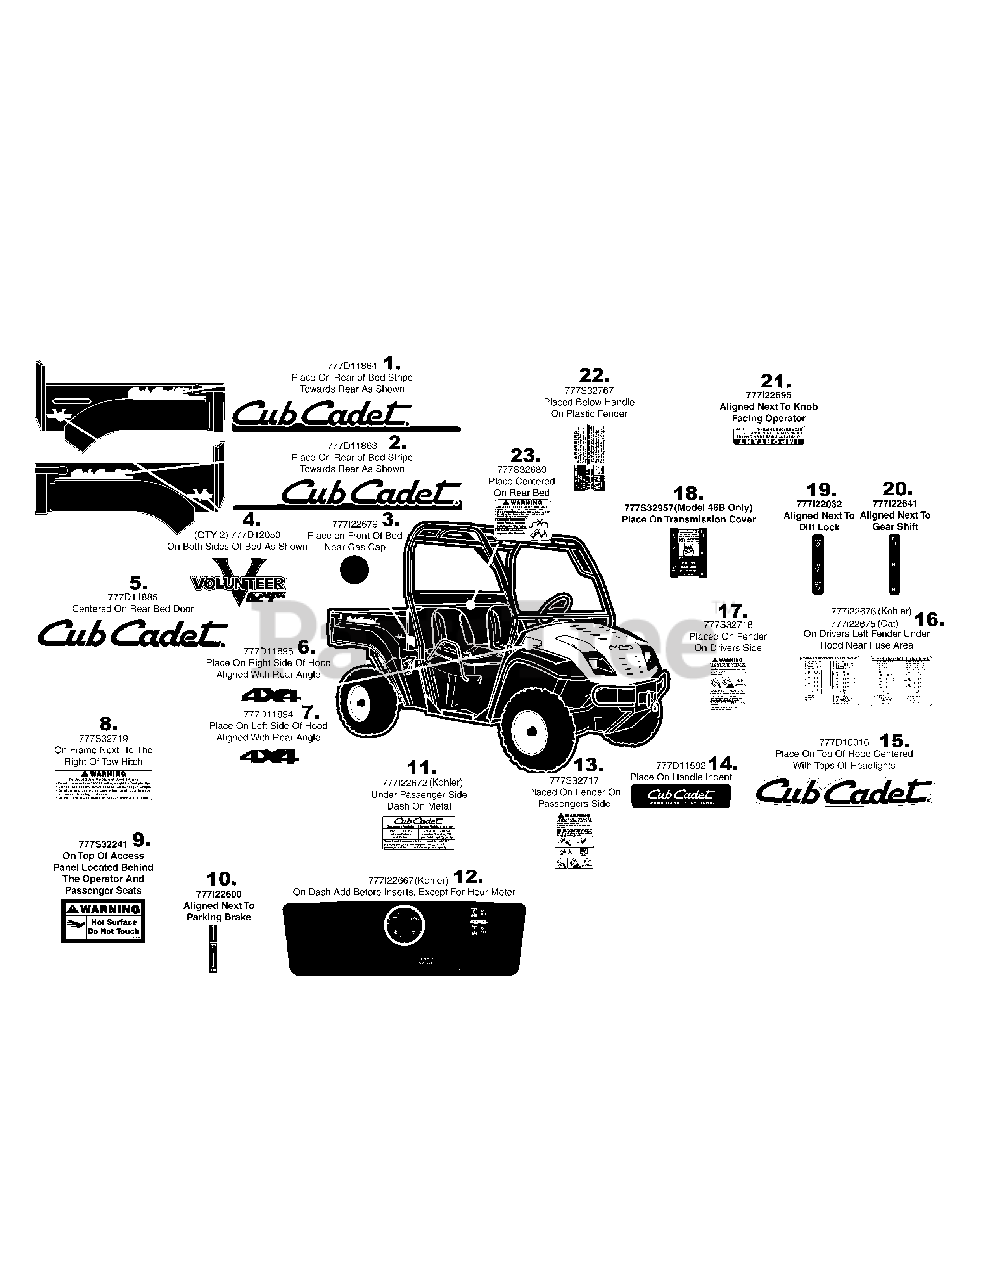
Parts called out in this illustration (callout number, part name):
1	LABEL-UV CUB EURO LEFT
2	LABEL-UV CUB EURO RIGHT
3	LABEL-CHECK ENG OIL
4	LABEL-UV VOL YELLOW BG 624
5	LABEL:UV:CUB CADET LOGO
6	LABEL-CUB UV 4X4 HOOD RIGHT SIDE
7	LABEL-CUB UV 4X4 HOOD LEFT SIDE
8	LABEL-TOW HITCH
9	LABEL-HOT SURFACE
10	LABEL-PARK BRAKE
11	LABEL-OPERATING WGT AIR COOL
12	LABEL-DASH
13	LABEL-RIDER FALL RH FENDER
14	LABEL-UV CUB DASH LOGO
15	LABEL-CUB CADET HOOD
16	LABEL:UV:4X4 KOHLER FUSE
17	LABEL-ROLL & FALL LH FENDER
18	LABEL:CUB:BENCH SEAT WARN
19	LABEL-DIFF LOCK CO
20	LABEL-GEAR SHIFT
21	LABEL:4X4 SHIFT
22	LABEL-4X4 CARGO BOX HANDLE
23	LABEL-CARGO LOAD
